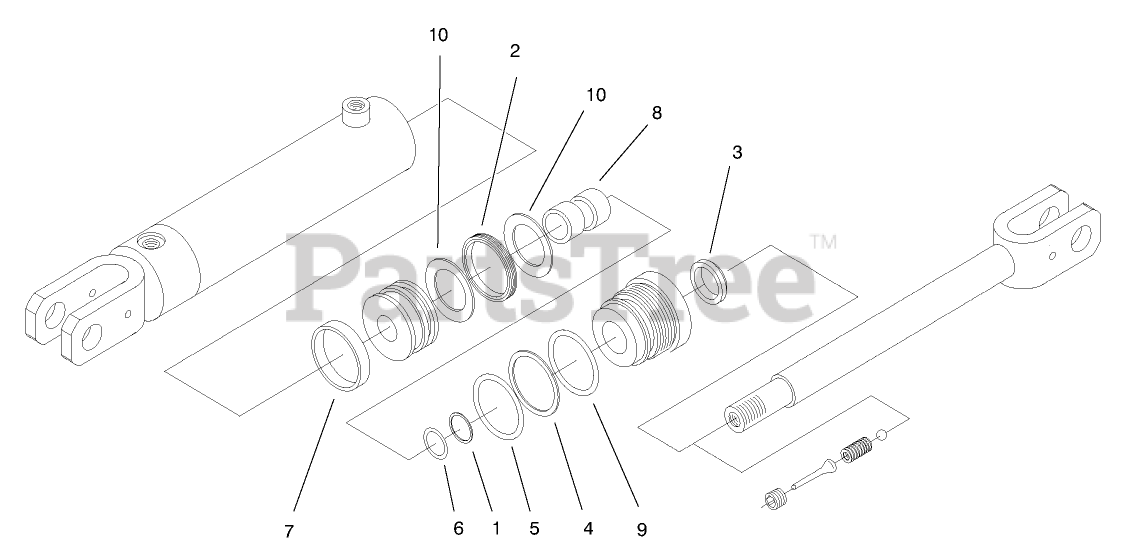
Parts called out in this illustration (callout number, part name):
2	PSP Seal
3	Rod-Wiper
6	Polypak
7	Ring-WEAR
8	Ring-WEAR
